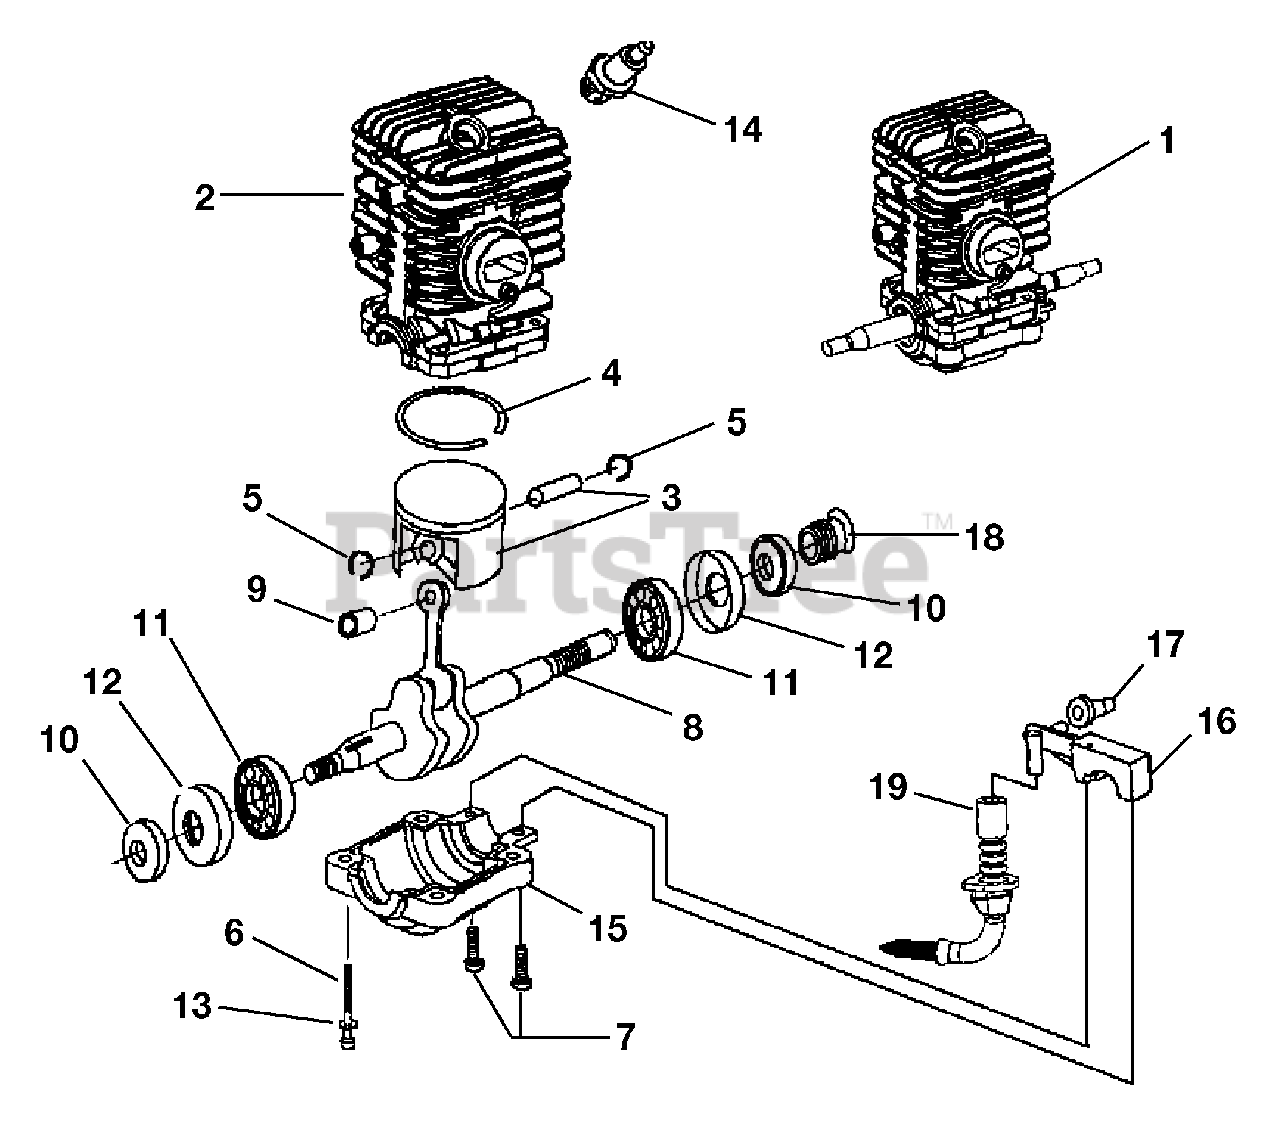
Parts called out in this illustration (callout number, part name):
1	Short Block, Complete (45cc)
2	Cylinder Kit (45cc)
3	Piston & Pin (45cc)
4	Piston Ring
5	Ring, Retaining
6	Screw, Cap-Socket Hd. (10-24 x 2")
7	Screw, Pan Hd, Plastite (8-32 x 5/8")
8	Crankshaft & Rod Assy
9	Bearing, Needle
10	Shaft Seal
11	Bearing & Rubber Case
12	Bearing Case
13	Washer
14	Spark Plug
15	Lower Crankcase
16	Oil Pump Kit
17	Grommet, Oil Outlet
18	Left Hand Worm
19	Oil Intake Tube w/Filter
